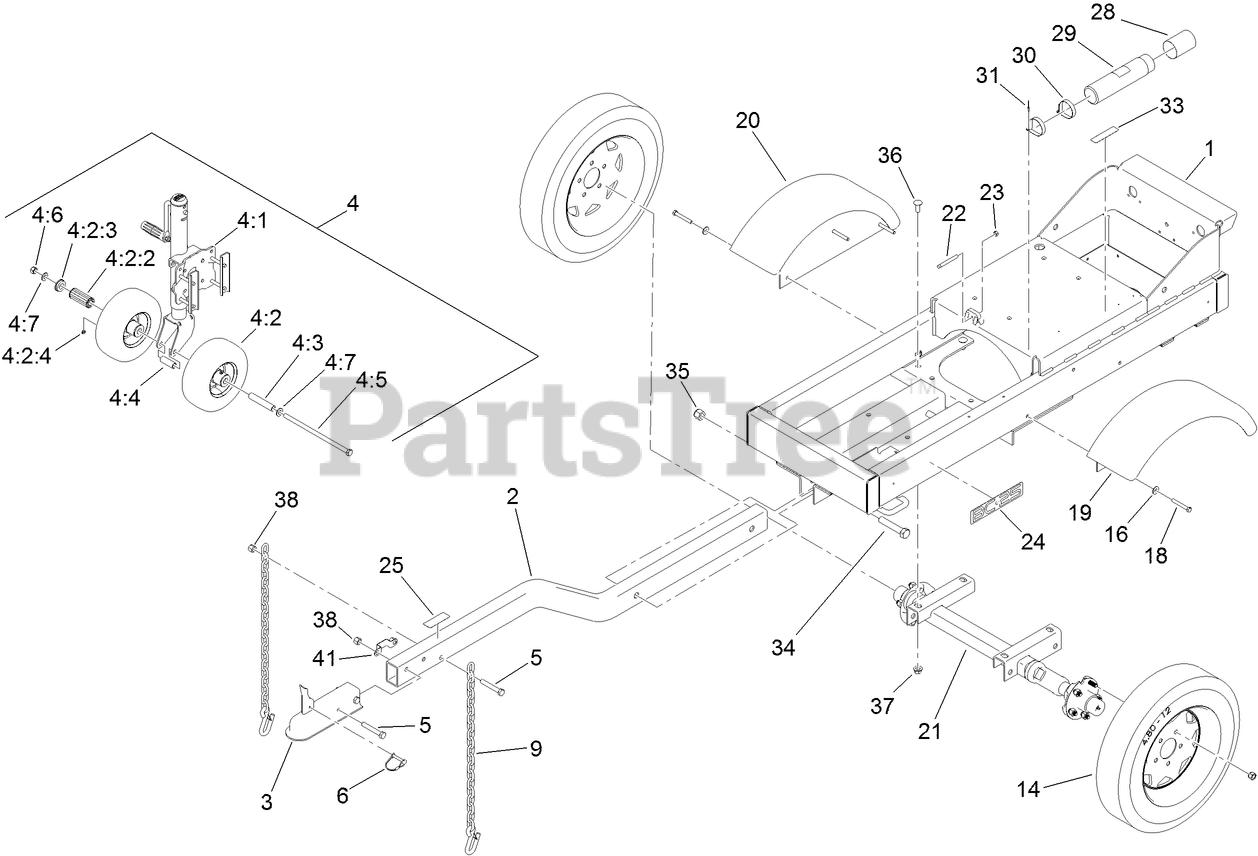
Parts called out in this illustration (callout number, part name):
1	CHIPPER TRAILER ASM
2	TUBE-TONGUE
3	RECEIVER-HITCH, BALL
4	JACK ASM
4:1	JACK-TRAILER
4:2	WHEEL AND TIRE ASM
4:2:2	BEARING-ROLLER
4:2:3	BUSHING
4:2:4	FITTING-GREASE
4:3	BUSHING-SPANNER
4:4	SPACER
4:5	SCREW-HH
4:6	NUT-HEX
4:7	WASHER-FLAT
5	SCREW-HH
6	PIN-LOCK
9	CHAIN-SAFETY, TRAILER
14	WHEEL AND TIRE ASM
16	WASHER-FLAT
18	SCREW-HH
19	LEFT FENDER ASM
20	RIGHT FENDER ASM
21	AXLE ASM
22	SCREW-SET, SQH
23	NUT-HEX
25	DECAL-CAUTION
28	CAP-HOUSING
29	TUBE-MANUAL
30	CLAMP-R
31	RIVET-POP
33	DECAL-ARRESTER, SPARK
34	SCREW-HH
35	NUT-LOCK, NI
36	SCREW-CARR, SHORT NECK
37	NUT-LOCK
38	NUT-LOCK, NI
41	BRACKET-RETAINER
